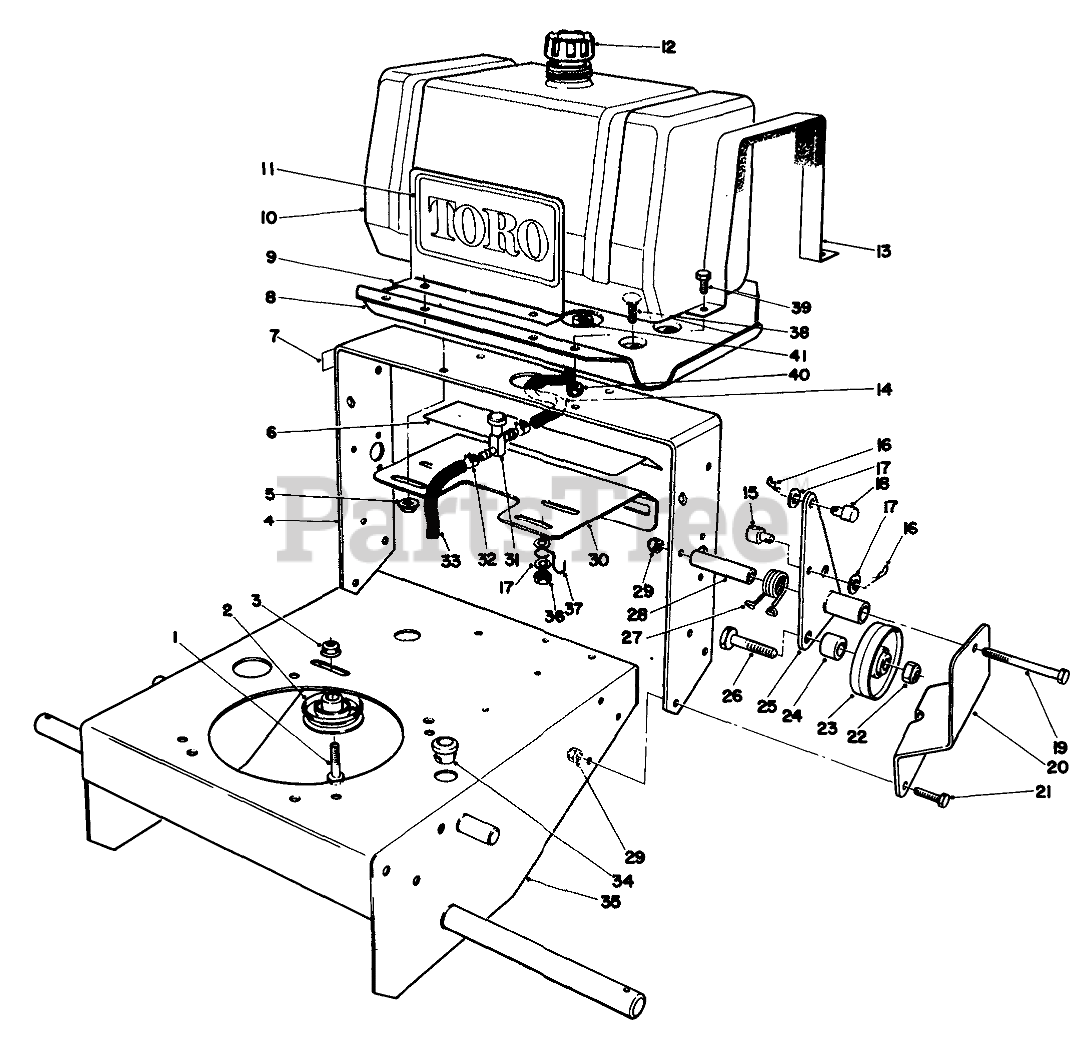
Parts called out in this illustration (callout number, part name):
1	SCREW-HH
2	PULLEY-IDLER
3	NUT-HF
4	Frame-Rear
5	NUT-HF
6	Decal-Ground Speed
7	Decal-Fuel Shut Off
8	PLATE-FUEL TANK
9	DECAL-PLATE
10	TANK-FUEL
11	DECAL
12	CAP-FUEL ASM
13	STRAP ASM
14	HOSE-FUEL
15	ROD FITTING
16	PIN-COTTER
17	WASHER-PLAIN
18	ROD FITTING
19	SCREW-HH
20	Support-Idler L.H.
21	SCREW-HH
22	NUT-LOCK, NI
23	IdlerWheel
24	WHEEL IDLER SPACER
25	LH IDLER BRKT WA
26	SCREW-LEVELER
27	SPRING-TORSION, LH
28	PIVOT-IDLER SPACER
29	NUT-LOCK, NI
30	Plate
31	FUEL VALVE
32	CLAMP-HOSE
33	HOSE-FUEL
34	GROMMET
35	Frame
36	NUT-LOCK, NI
37	GAS LINE CLIP
38	SCREW-CARR
39	SCREW-HH
40	NUT-LOCK, NI
41	CLAMP-HOSE
